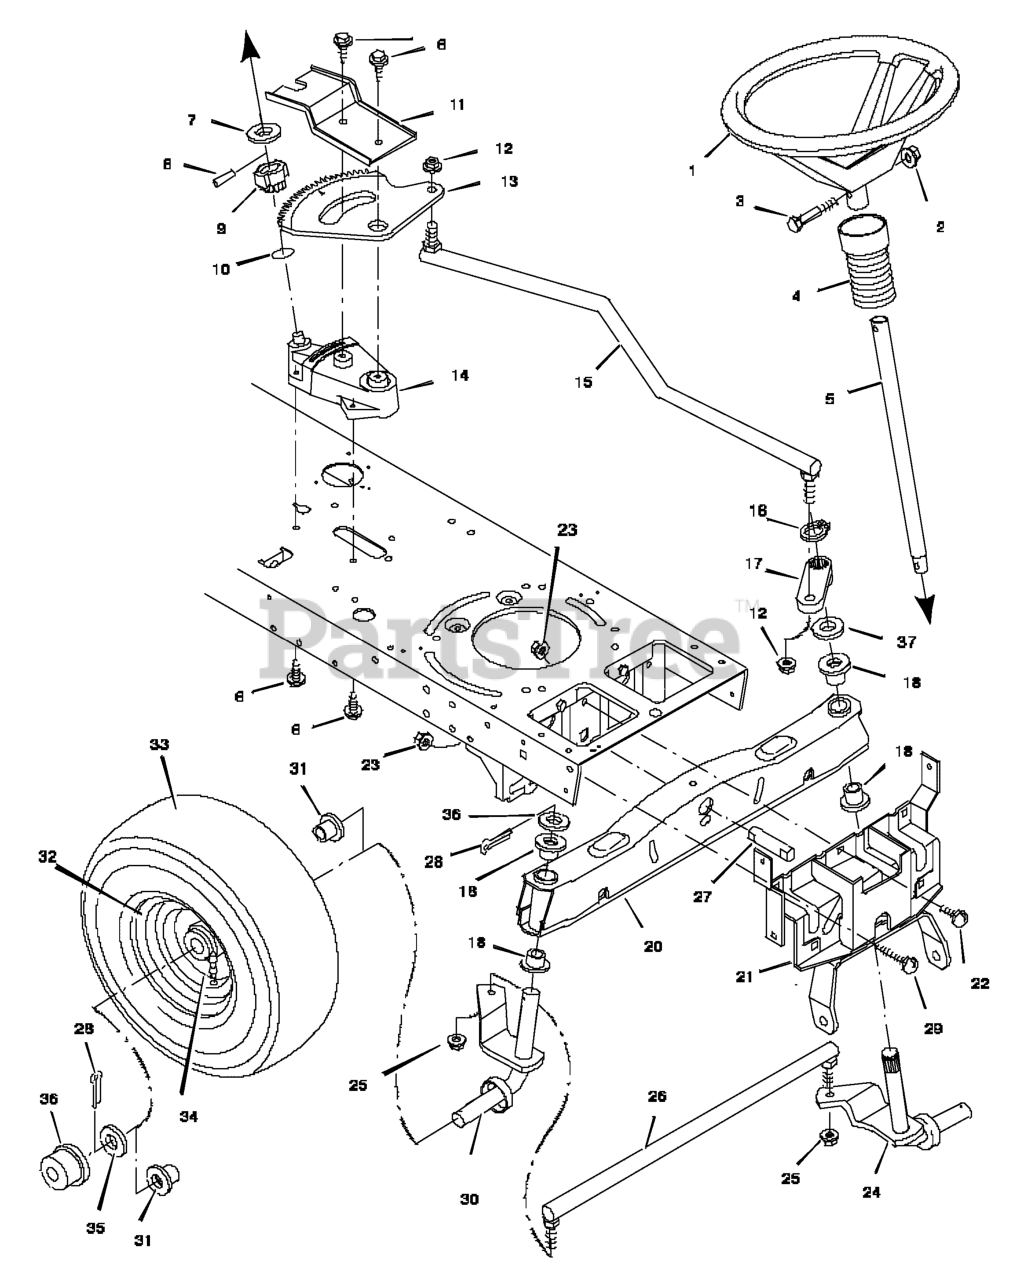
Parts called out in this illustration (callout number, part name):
1	Wheel, Steering
2	Nut, Hex
3	Bolt, Hex
4	Bellows
5	Post Assembly, Steering
7	Washer
8	Pin, Spring
9	Gear Assembly, Pinion
10	O-Ring
11	Clip, Gear Retainer
12	Locknut, Flange
13	Gear, Sector
14	Support, Steering
15	Link, Drag
16	E- Ring
17	Arm, Drag Link
18	Bearing
20	Axle Assembly (with grease fittings)
21	Hanger Assembly, Axle
22	Bolt, Carriage
23	Locknut, Flange
24	Spindle Assembly, Left
25	Locknut, Flange
26	Rod, Tie
27	Pin, Pivot
28	Pin, Cotter
29	Bolt, Carriage
30	Spindle Assembly, Right
31	Bearing, Wheel
32	Wheel & Tire Assembly
33	Tire *
34	Stem, Valve
36	Hub Cap
